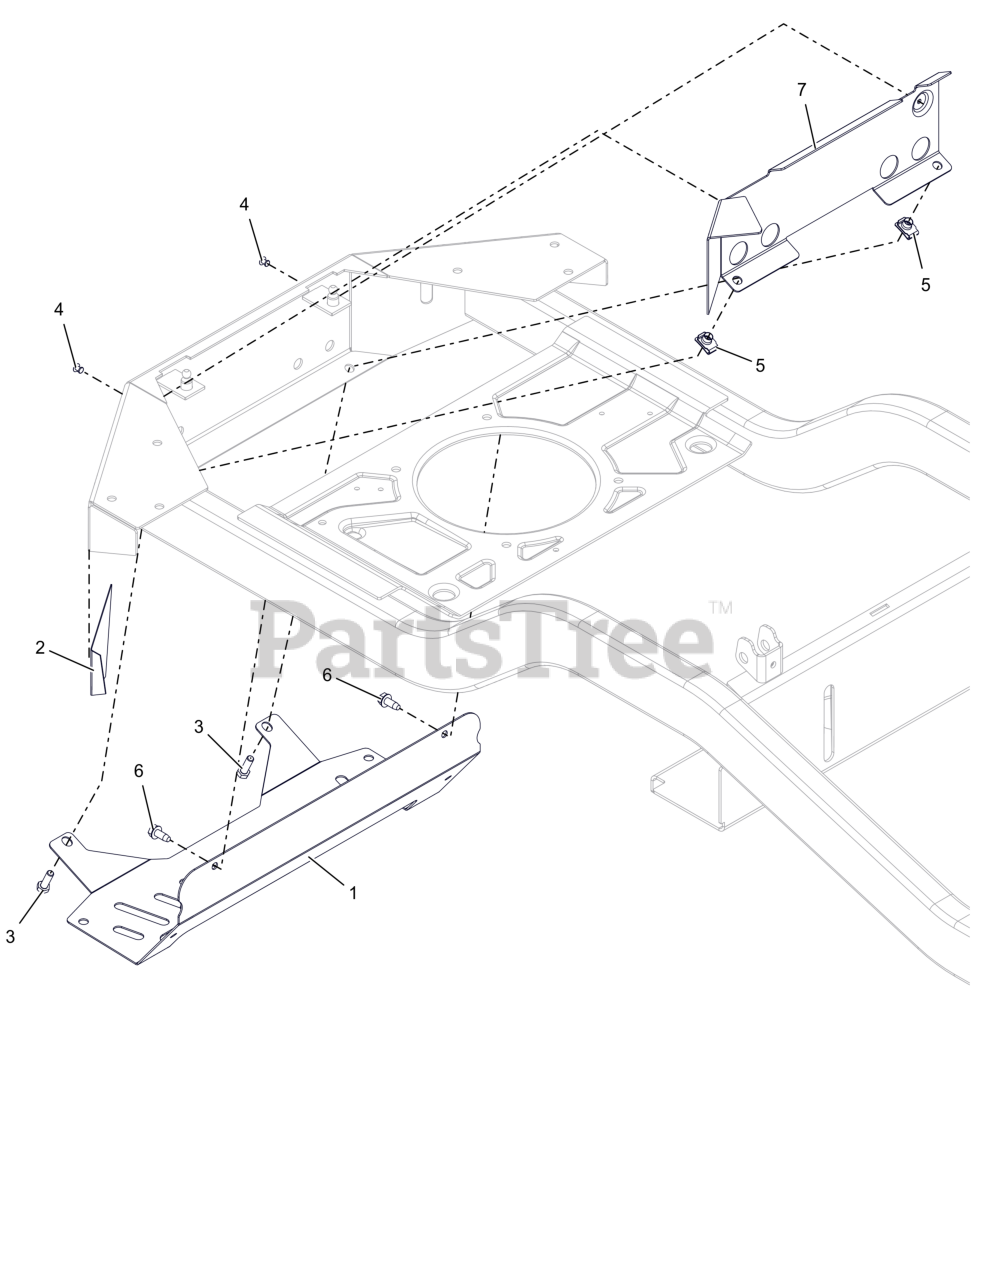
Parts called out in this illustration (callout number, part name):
1	SHIELD, HEAT (HD)
2	TAPE, HEAT DEFLECTOR
3	BLT,HEX .31-18X1.00 G5 ZCC
4	RVT-POP .187x.250 (#64) BLK
5	NUT-CLIP RETAINER 5/16-18X.56
6	SCR,TAP .312-18X.75 HWH TR ZCC
7	BAFFLE, HEAT SHIELD (BLACK)
